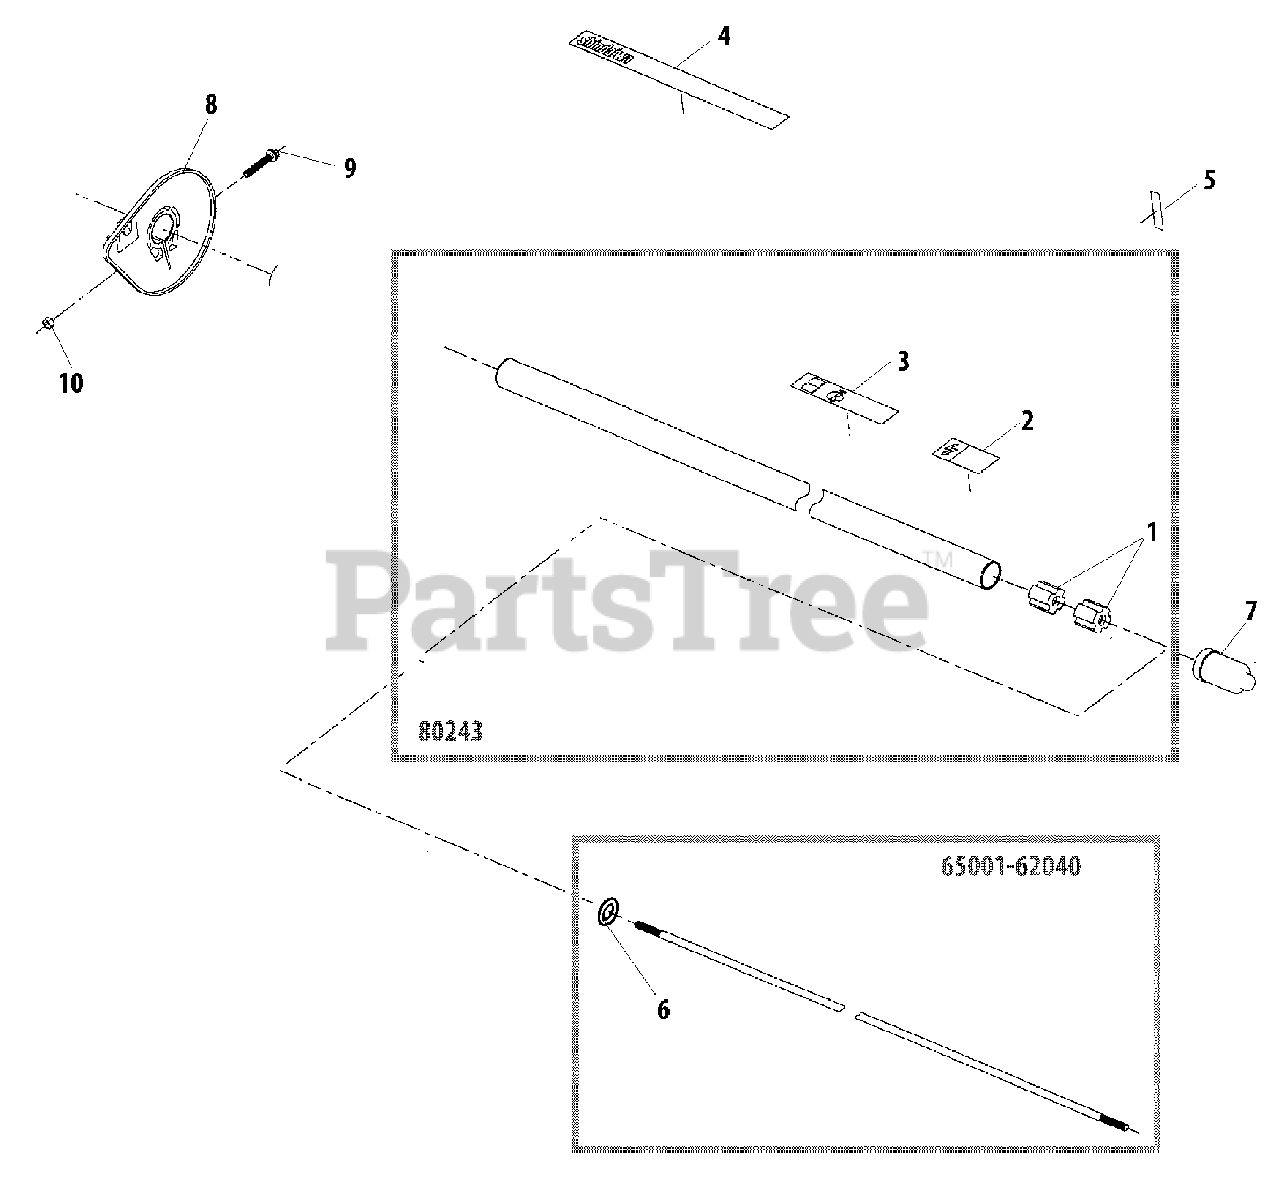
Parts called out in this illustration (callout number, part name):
1	BUSHING
2	LABEL - HIGH VOLTAGE
3	LABEL - CAUTION
4	LABEL - NAME
5	LABEL - ALIGNMENT
6	GROMMET
7	CAP
8	PROTECTOR
9	SCREW - 5X30
65001-62040	DRIVESHAFT ASSY
80243	MAIN PIPE ASSY
